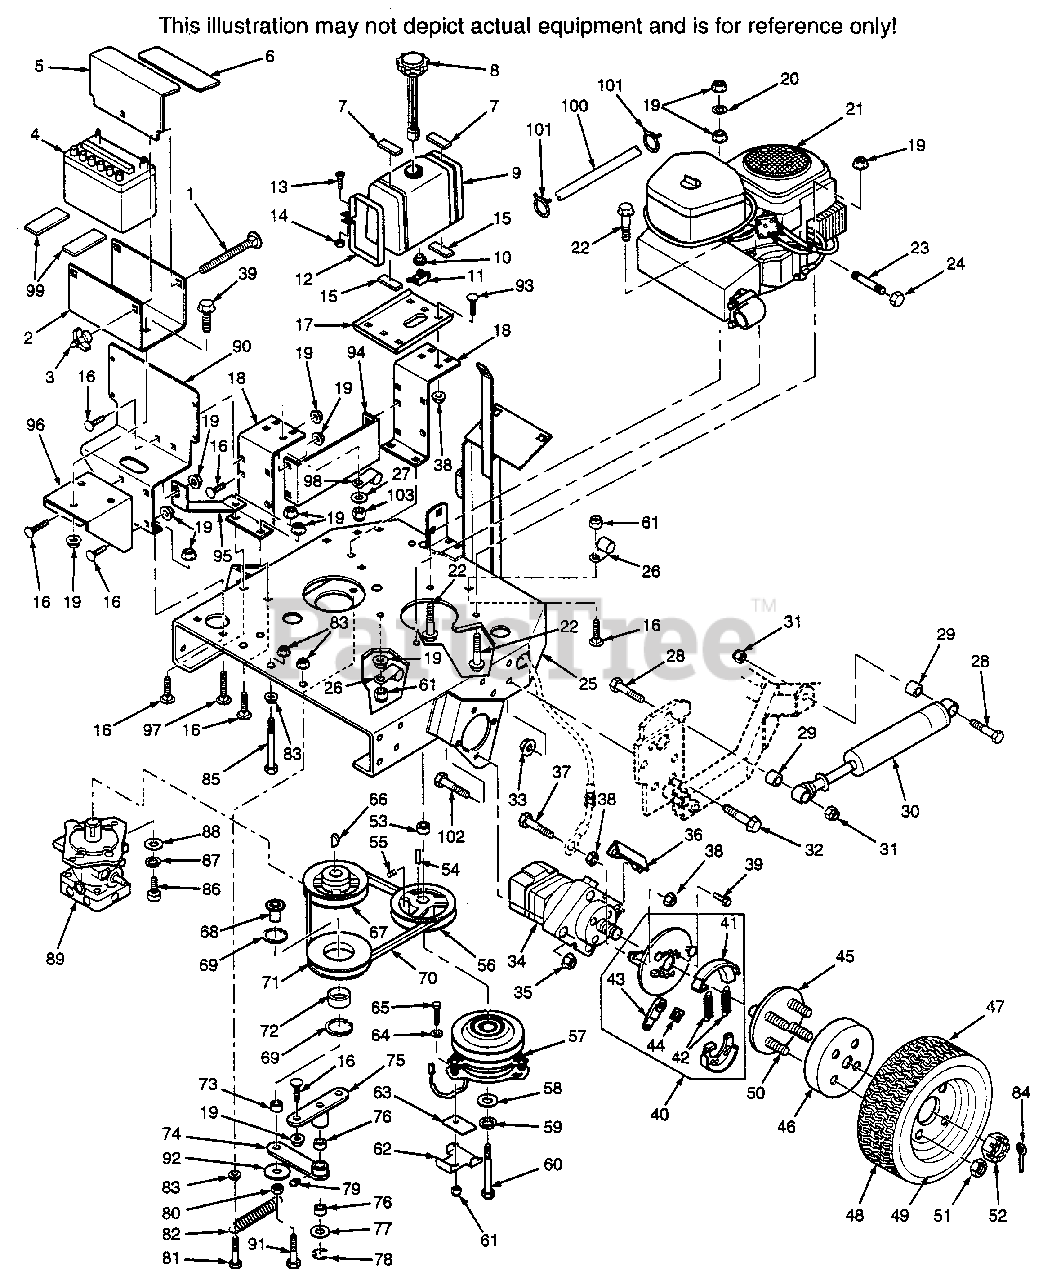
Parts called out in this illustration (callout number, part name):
1	CARRIAGE BOLT, 1/4-20 X 6
2	BATTERY BOX
3	NUT, WING 1/4-20
4	BATTERY
5	BATTERY COVER
6	INSULATION, BATTERY COVER
7	PAD, FUEL TANK STRAP
8	CAP, FUEL TANK
9	FUEL TANK ASSY.(INCLUDES ITEMS 10-11)
10	BUSHING, FUEL TANK VALVE
11	FUEL SHUT OFF VALVE
12	STRAP, FUEL TANK
13	PHIL RDHD MACHINE SCREW 1/4-20 X 2
14	HEX NUT, 1/4-20
15	PAD, FUEL TANK SUPPORT
16	CARRIAGE BOLT, 5/16-18 X 3/4
17	SUPPORT, FUEL TANK
18	BRACKET, FUEL TANK SUPPORT
19	SERR. FL. HEX NUT 5/16-18
20	LOCKWASHER, 5/16 INT. TOOTH
21	ENGINE, 20 HP KOHLER CV
21	ENGINE, 22 HP KOHLER CV
22	SERR. FL. HEX HEAD CPSCR, 5/16-18 X 1 3/4
23	OIL DRAIN EXTENSION
24	CAP, PLUG
25	ENGINE DECK
26	WIRE LOOM, .50 I.D.
28	BOLT, HEX HEAD 1/2-13 X 2
29	SLEEVE, SHOCK ABSORBER MOUNT
30	SHOCK ABSORBER
31	HEX LOCKNUT, ELASTIC STOP 1/2-13
32	SERR. FL. HEX HEAD CPSCR, 7/16-14 X 1
33	SERR. FL. HEX NUT, 7/16-14
34	MOTOR - WHITE(INCLUDES ITEM 52)
35	SERR. FL. HEX NUT, 1/2-13
36	ANCHOR, BRAKE
37	BOLT, HEX HEAD 1/4-20 X 1-1/4
38	SERR. FL. HEX NUT, 1/4-20
39	SERR. FL. HEX HEAD CPSCR, 5/16-18 X 3/4
40	PARKING BRAKE ASSEMBLY
41	BRAKE PADS-PAIR
42	SPRINGS - PAIR
43	ACTUATING ARM,(INCL. PIN & CLIP)
45	HUB ASSEMBLY(INCLUDES ITEM 50)
46	BRAKE DRUM
47	RIM AND TIRE ASSEMBLY(INCLUDES ITEMS 48,49)
48	TIRE 20 X 10 X 10, 4 PLY
49	RIM ONLY
50	BOLT, HUB
51	WHEEL NUT
52	SPRING LOCKNUT
52	CASTLE NUT, 1.0-20 UNEF
53	SPACER, CLUTCH
54	KEY, 1/4 X 1/4 X 1-1/2
55	HEX SOCKET SET SCREW, 5/16-18 X 3/8
56	PULLEY, ENGINE PUMP DRIVE(INCL. 55)
57	CLUTCH, ELECTRIC
58	FLATWASHER, 7/16(.469 X 1.50 X .25)
59	LOCKWASHER, 7/16
60	BOLT, HEX HEAD 7/16-20 X 3
61	HEX LOCKNUT, ELASTIC STOP 5/16-18
62	BACKING PLATE, CLUTCH STOP
63	RUBBER PAD, CLUTCH STOP
64	FLATWASHER, 5/16(.375 X .875 X .083)
65	BOLT, HEX HEAD 5/16-18 X 1-1/4
66	KEY, WOODRUFF 3/16 X 5/8
67	PULLEY, PUMP INPUT
68	SLEEVE, IDLER
69	RING, RETAINING, 1-9/16 INTERNAL
70	BELT, PUMP DRIVE
71	PULLEY, IDLER-TRACTION DRIVE(INCL.68,69,72)
72	BEARING, IDLER PULLEY
73	SPACER, IDLER
74	PUMP IDLER ARM(INCLUDES ITEMS 76,79)
75	IDLER PIVOT BASE
76	BUSHING, OILLUBE
77	FLATWASHER, 3/4
78	RING, RETAINING, 3/4 EXT. "E"
79	GREASE FITTING
80	HEX NUT, JAM 3/8-16
81	BOLT, HEX HEAD 3/8-16 X 3-1/4
82	SPRING, PUMP DRIVE IDLER
83	SERR. FL. HEX NUT, 3/8-16
84	COTTER PIN, 5/32 X 1.50
85	BOLT, HEX HEAD 3/8-16 X 5
86	SOCKET HEAD CPSCR, 1/2-13 X 1-1/4
87	LOCKWASHER, 1/2
88	FLATWASHER, 1/2(.516 X .938 X .05)
89	PUMP, SUNDSTRAND
90	BRACKET, OIL TANK SUPPORT
91	BOLT, HEX HEAD 3/8-16 X 1-3/4
92	WASHER 2" OD, 3/8 ID, 16 GA.
93	CARRIAGE BOLT, 1/4-20 X 3/4
94	GUARD, PULLEY
95	GUSSET, BATTERY BOX
96	SUPPORT, BATTERY BOX
98	WIRE LOOM, .75 I.D.
99	RUBBER PAD
100	FUEL HOSE, 26"
101	CLAMP, FUEL HOSE
102	BOLT, 1/2-13 X 2.50"
103	NUT, 1/4-20 ELASTIC STOP
